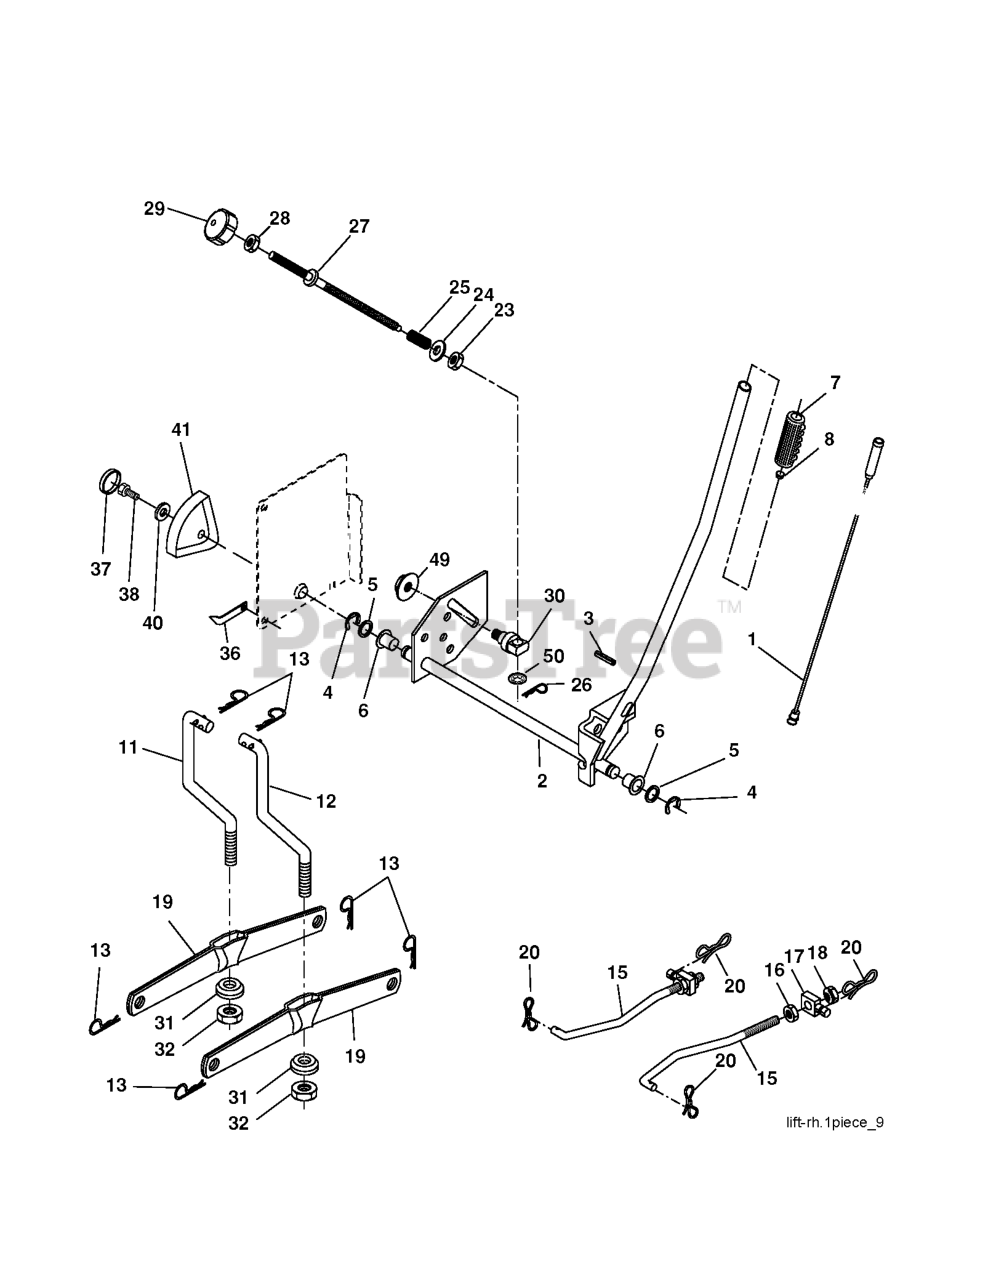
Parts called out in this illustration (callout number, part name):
1	WIRE ASM INNER W/ PLUNGER LT
2	SHAFT ASM R HANDLE
3	PIN GROOVE.
4	RETAINING RING LT
6	BEARING.NYLON
7	GRIP HANDLE
8	PLUNGER BUT KIT
11	LINK
12	LINK
13	RETAINER-SPRNG RB
15	LINK.SUSPENSION.FRONT
16	NUT.HEX.JAM.1/2-13
18	NUT.LK.W/WSH.1/2.
19	ARM.REAR.SUSPENSION
20	PIN.COTTER.7/16.BOW TI.
25	SPRING**
26	RETAINER CLIP
27	ROD ADJ LIFT
28	NUT
29	KNOB INF 3/8-16
31	BEARING.PIVOT.LIFT
32	NUT CROWNLOCK 3/8-24
36	POINTER, HEIGHT INDICATOR(2 2)
38	SCREW 5/16-18X1
41	HEIGHT INDICATOR
49	NUT
50	NUT PUSH M
